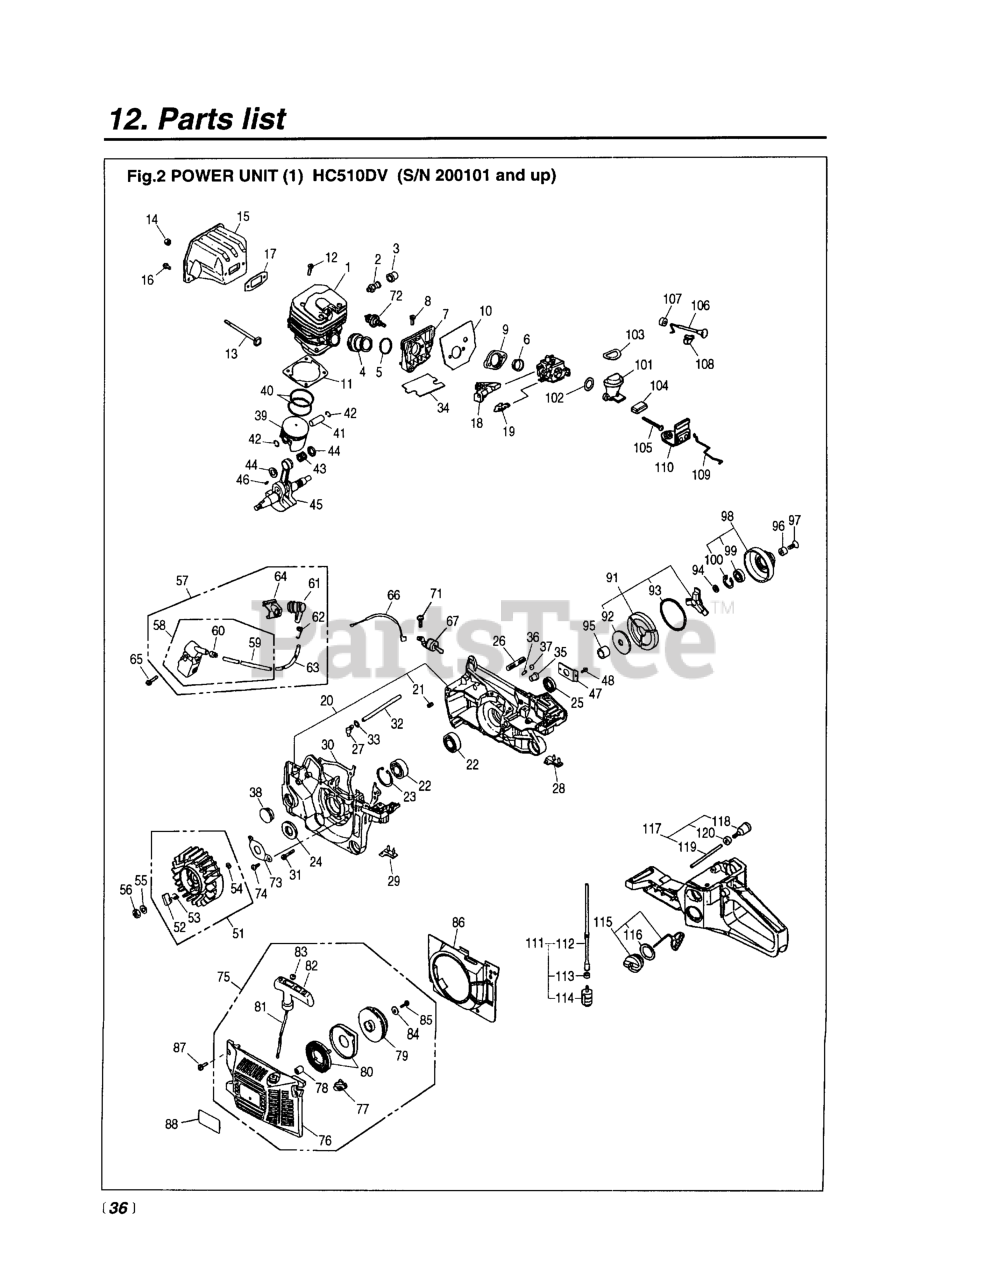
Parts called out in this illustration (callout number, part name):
1	CYLINDER
2	VALVE ASSY.
4	PIPE
5	SPRING
6	GUIDE
8	SCREW (REPLACES 2616-24320)
10	GASKET (RPLS 2880-14360)
11	GASKET, CYLINDER (RPLS -14210)
13	BOLT
14	NUT, MUFFLER (RPLS 3356-15230
16	SCREW
17	GASKET
20	CRANKCASE ASSY.
22	BEARING (REPLACES 2810-21240)
23	RING, SNAP, M35 X 1.5
24	SEAL, OIL
25	SEAL, OIL
28	STOPPER, REAR (RPLS 2670-22510
29	STOPPER, REAR
34	MAT (RPLS 2810-22410)
36	VALVE (RPLS -23120)
37	CLIP
39	PISTON
40	PISTON RING
41	PIN, PISTON
42	RING, SNAP
43	BEARING
44	WASHER, THRUST
45	CRANKSHAFT COMP.
46	KEY
53	SPRING, RETURN
54	RING, SNAP, M4
55	WASHER, M8 x 20
56	NUT (RPLS -43230)
57	COIL ASSEMBLY
58	COIL COMPLETE
59	CORD, HI TENSION
61	CAP, PLUG
62	SPRING PLUG (RPLS 3310-71320)
67	SWITCH ASSY.
71	SCREW
72	PLUG, BPM8Y
74	SCREW, M4 X 10
75	STARTER ASSY.
76	CASE, RECOIL (RPLS 2670-75113)
79	REEL (REPLACES -75211)
80	SPRING COMP
82	KNOB
84	WASHER (USE 181741)
86	COVER COMPLETE
87	SCREW (REPLACES 2616-24320)
91	CLUTCH ASSY (RPLS -51200)
92	PLATE
93	SPRING (RPLS -51230)
98	CLUTCH DRUM ASSY.
100	RING, SNAP, M30 X 1.2
101	MANIFOLD
104	SUPPORTER
106	ROD, CHOKE
108	GUIDE
109	ROD, THROTTLE
114	FILTER ASSY
115	CAP ASSEMBLY
116	GASKET
117	BREATHER ASSY.
118	BREATHER ASSEMBLY
119	PIPE, SUCTION
